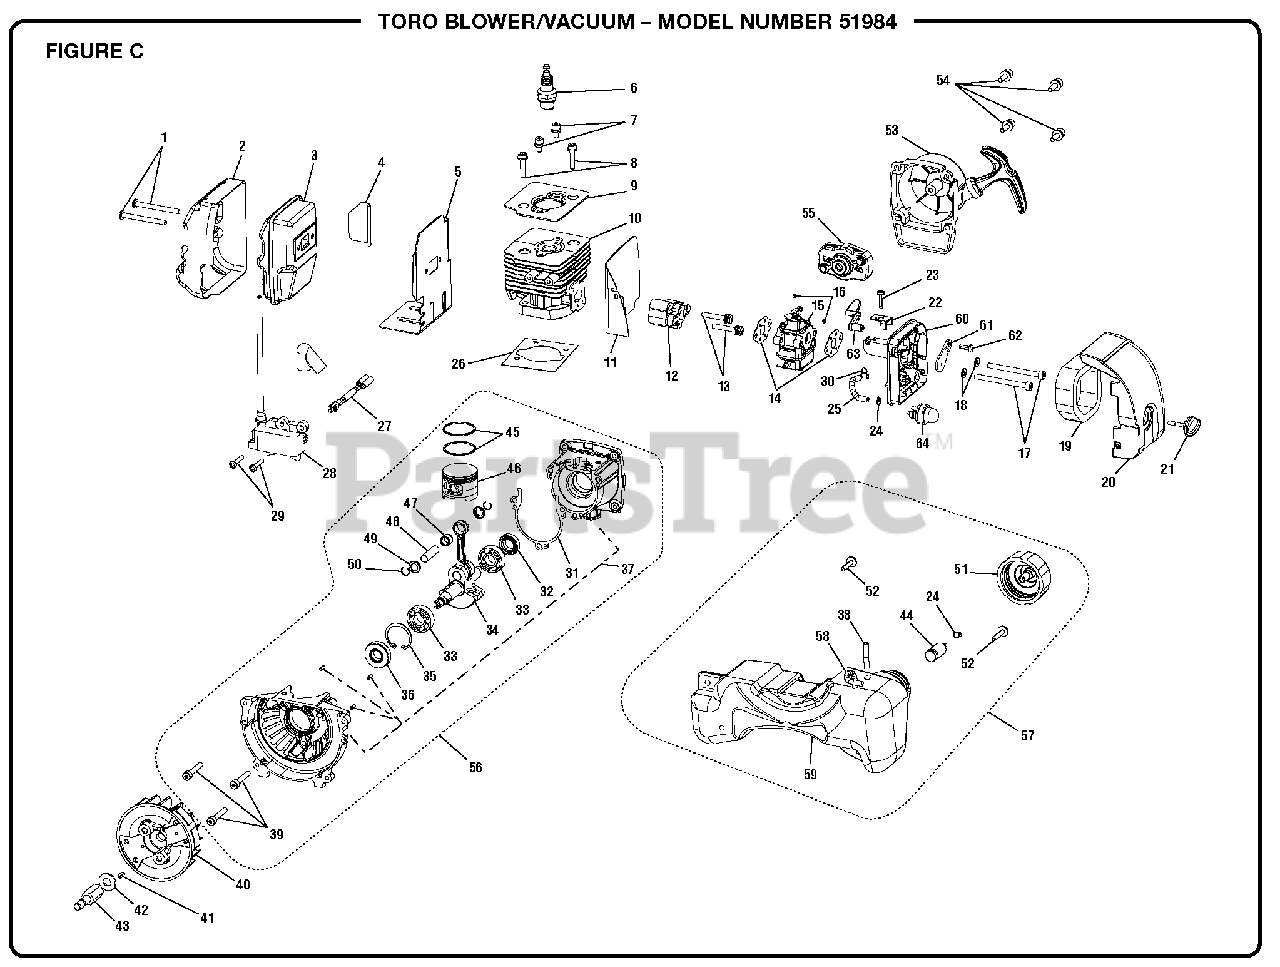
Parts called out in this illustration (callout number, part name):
2	Heat Shield (Carb)
4	Heat Shield
5	Muffler Gasket Stamping
6	Spark Plug
7	Screw (M5 x 10)
8	Screw (M5 x 22)
9	Cylinder Stamping
10	Cylinder
11	Gasket Insulator
12	Plastic Heat Dam
13	Screw and Washer (M5 x 31)
14	Heat Dam. Gasket
15	Carberator Assembly
17	Bolt (M5 x 44)
19	Air Filter
20	Air Box Cover
21	Knob
22	Retaining Clip
24	Steel Hose Clip
27	Ignition Lead Assembly
28	Ignitioon Coil Assembly
30	Steel Hose Clip
31	Crankcase Gasket
32	Seal (Starter Side)
33	Ball Bearing
34	Crankshaft Assembly
35	Internal Retaining Ring
36	Seal (Flywheel Side)
37	Crankcase
38	Rubber Tubing
41	Woodruff Key
43	Crankshaft Extension
44	Fuel Filter
45	Piston Ring
46	Piston Casing
47	Bearing Needle
48	Wrist Pin
49	Keeper Washer
50	Clip Ring
51	Fuel Cap Assembly
52	Screw
53	Recoil Starter Assembly
54	Screw and Washer (M5 x 16)
55	Pulley Assembly
56	Crankcase Assembly
57	Fuel Tank and Cap Assembly
58	Rubber Tubing
59	Fuel Tank
60	Air Box Case
61	Choke Plate
62	Screw
63	Choke Lever
64	Primer Bulb Assembly
